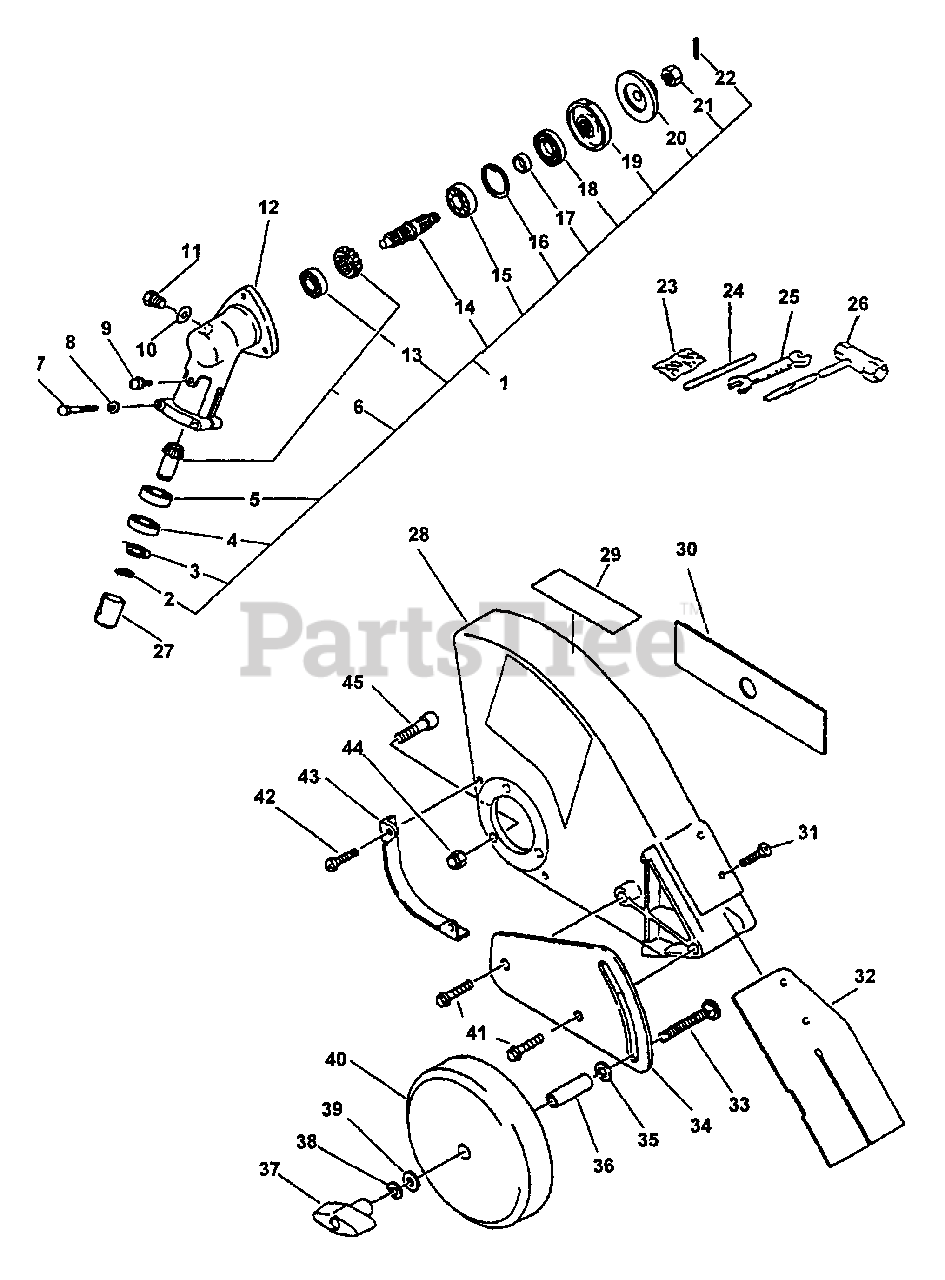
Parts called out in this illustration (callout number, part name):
1	GEAR CASE ASSY
2	RING, RETAINING - 18
3	RING, RETAINING
4	BEARING, BALL - 609
5	BEARING, BALL - 609
6	GEAR SET
7	BOLT - 5X30
8	WASHER - 5
9	SCREW - 5X12
11	FITTING, GREASE
12	CASE, GEAR
13	BEARING, BALL - 629
14	GEAR - SHAFT
15	BEARING, BALL - 6201
16	RING, RETAINING - 20
18	SEAL, OIL
19	ADAPTOR, BLADE - LOWER
20	ADAPTOR, BLADE - LOWER
21	NUT - 10 -- LEFT HAND
22	PIN, SPLIT - 2X22
23	T-WRENCH - 17X19mm
24	SPANNER - 8X10mm
25	LOCKING TOOL
26	PIN, SPLIT - 2X22
27	COLLAR
28	SHIELD, DEBRIS
29	LABEL - CAUTION
30	BLADE, EDGER
31	SCREW - 3
32	FLAP, DEBRIS
33	BOLT - CARRIAGE
34	BRACKET, WHEEL
35	WASHER - 10
36	COLLAR - 12
37	WINGNUT - 5/16-18
38	LOCKWASHER - 8
39	WASHER - 8
40	WHEEL - 6X1.5
41	BOLT - 8
42	SCREW - 4X16
44	LOCKNUT - 5
45	SCREW - 5X22
